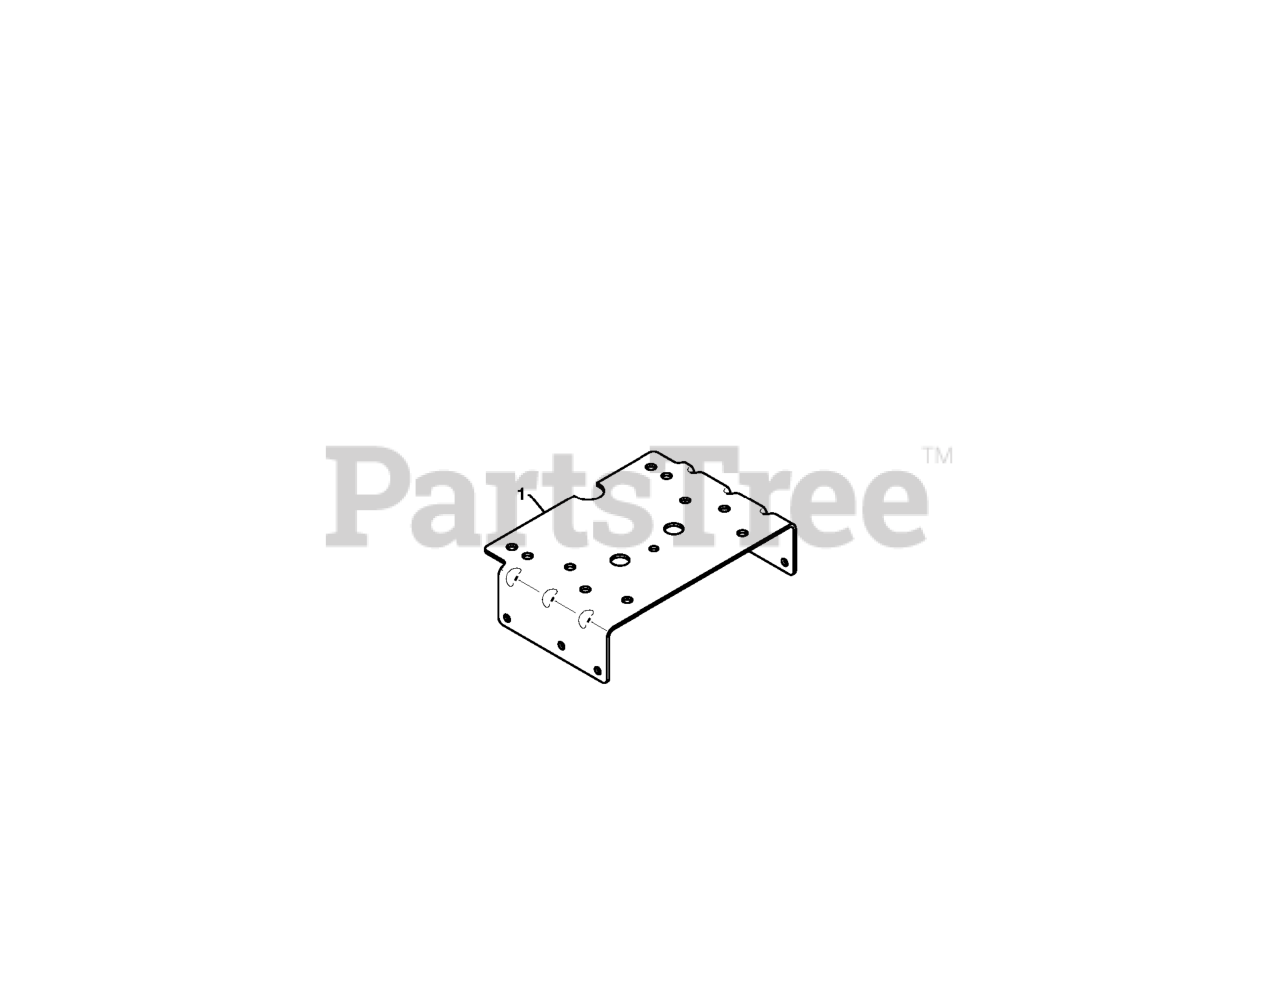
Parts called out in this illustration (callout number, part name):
1	PLATE.ENGINE.MOUNT.LCT.ORANGE
10	Screw M10x25
11	NUT
14	RETAINING RING SGA 25
17	BELT GUIDE
